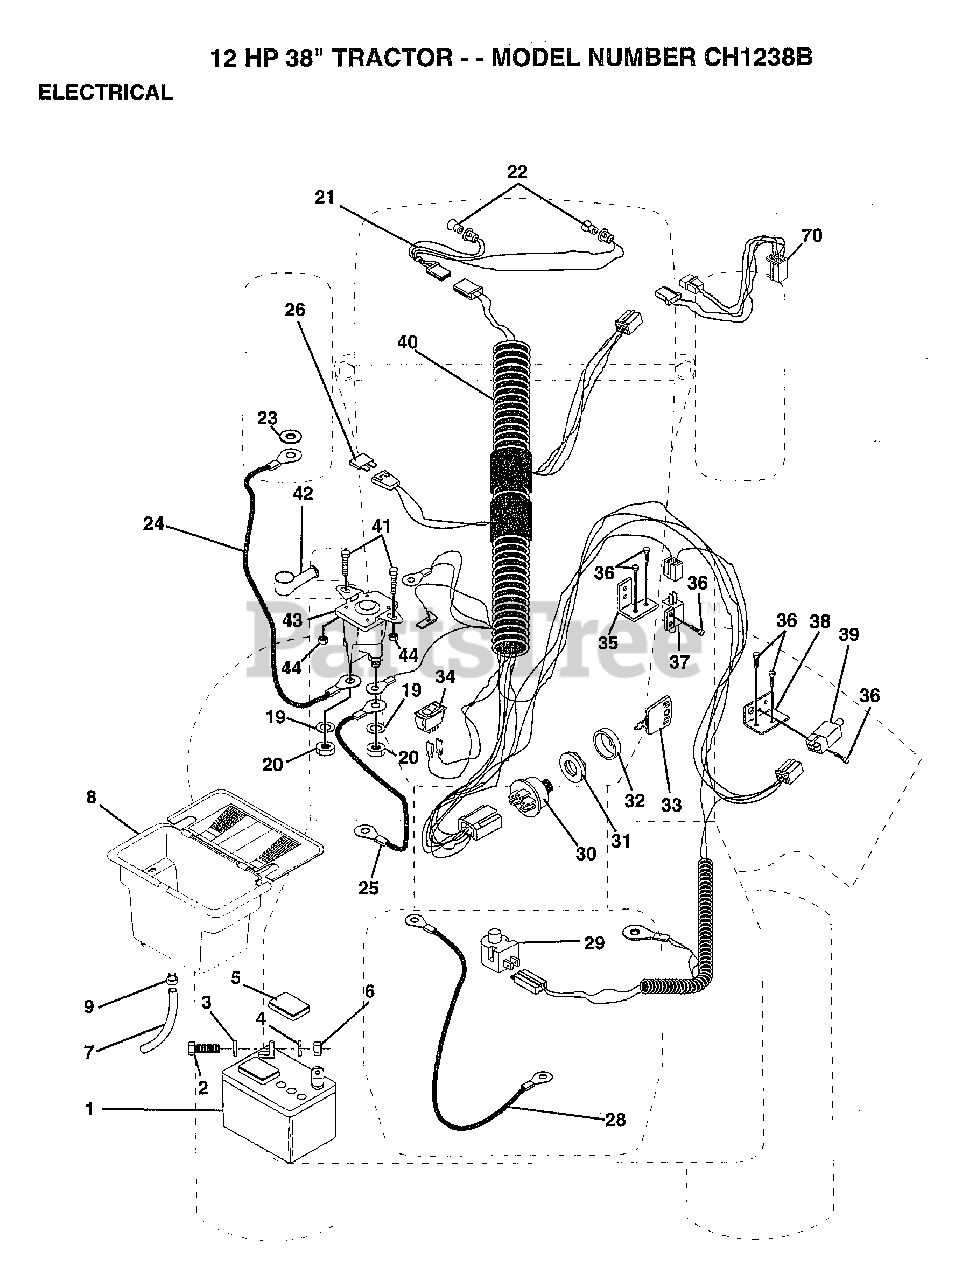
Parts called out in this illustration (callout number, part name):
2	BOLT LT
3	WASHER
4	LOCKWASHER
5	"CAP,BATTERY "
7	TUBE T
9	HOSE CLAMP T
20	NUT
21	"HARNESS,LIGHT SOC"
22	HEADLAMP BULB
23	LOCKWASHER
24	"CABLE T, BATTERY"
26	FUSE HYT
28	CABLE T
29	SWITCH SEAT
33	KEY MLD GEN DELTA
34	SWITCH LT
35	BRACKET LT
36	SCREW
37	SWITCH-INTER. GT
38	BRACKET SWITCH IN
39	SWITCH INTERLOCKT
40	HARNESS IGN DASH
41	BOLT HXHD FIN
44	NUT HXKEP 1/4X20
70	HARNESS.ENG.DUAL
